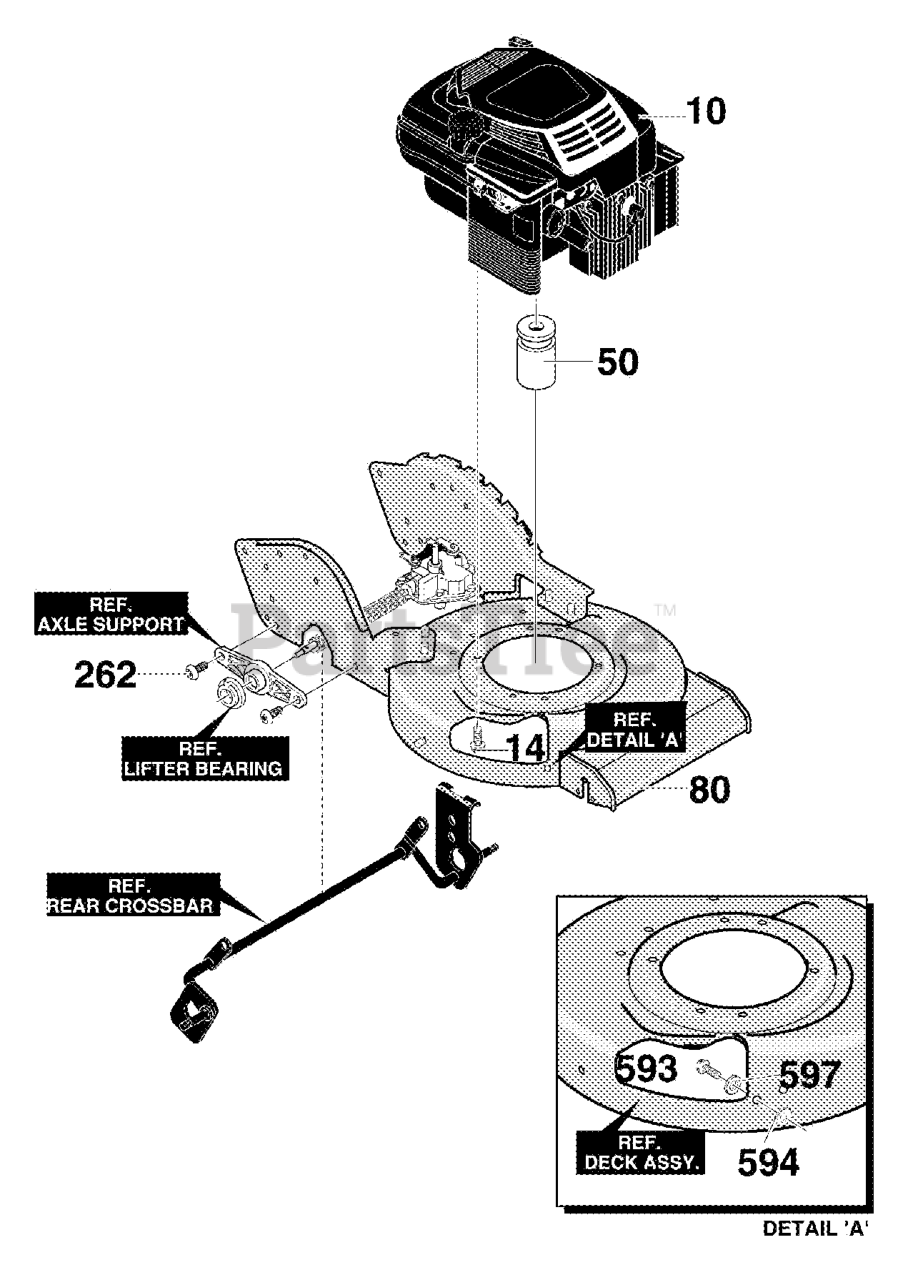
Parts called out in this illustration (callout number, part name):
10	Engine *
14	SCREW, 3/8-16 x 1.00
50	Adapter, Blade Pulley
80	FRAME Assy.
262	SCREW, 5/16-8 x .63
594	NUT, Retainer
597	FLATWASHER
